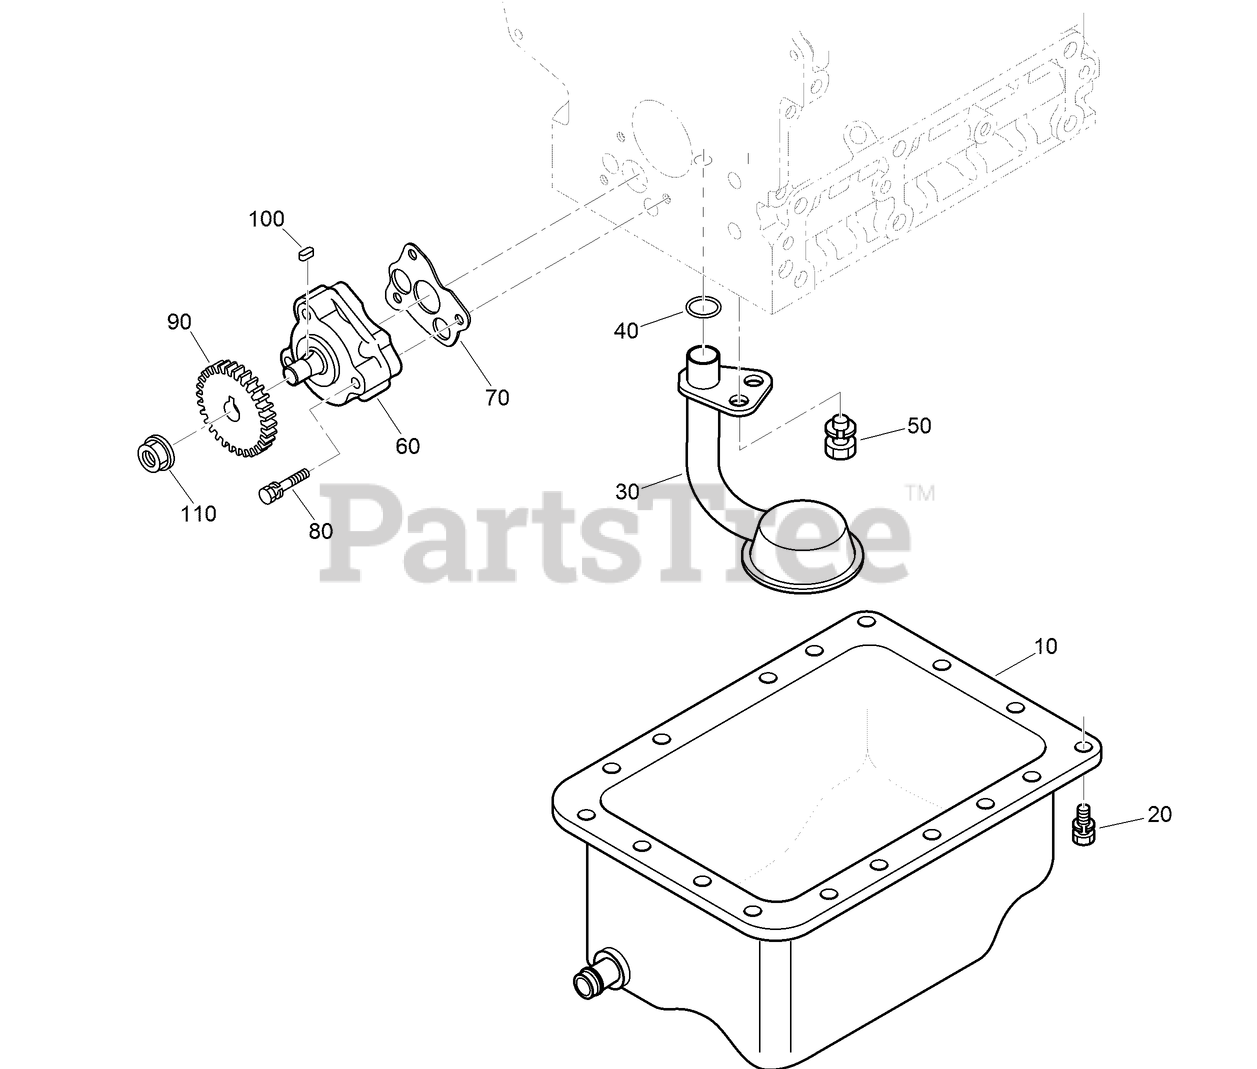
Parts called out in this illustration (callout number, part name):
10	PAN-OIL
30	STRAINER-PICKUP, OIL
40	O-RING
60	OIL PUMP ASM
70	GASKET-PUMP, OIL
90	GEAR-DRIVE, OIL PUMP
100	KEY-FEATHER
110	NUT-FLANGE
